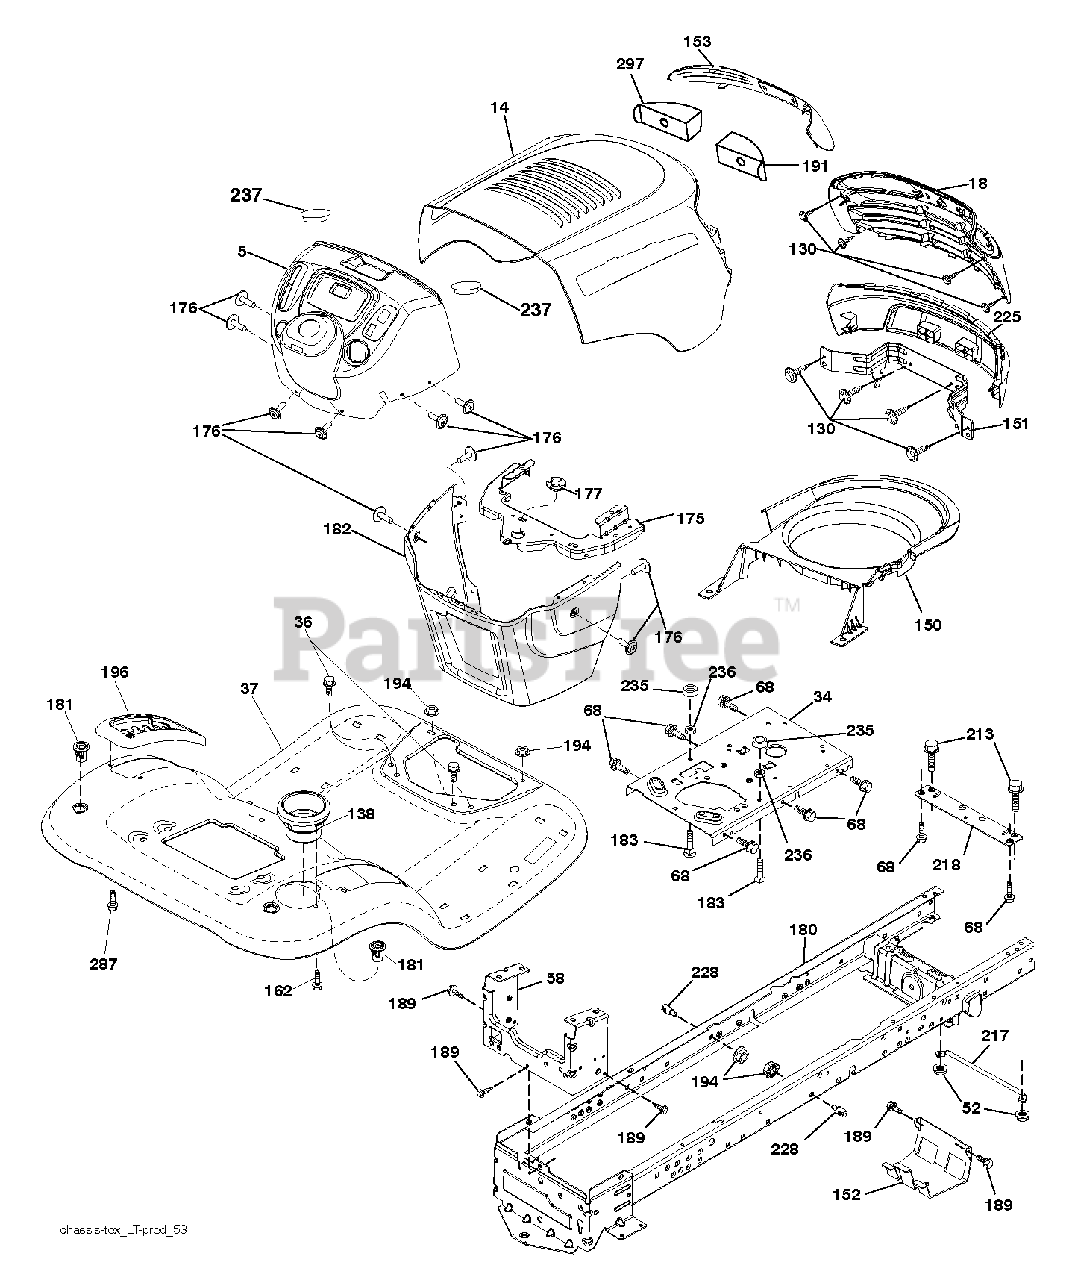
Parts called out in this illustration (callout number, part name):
5	DASH.PRED.LT.CC.ICY.N/SRV.BLK
14	HOOD.PREDATR.LT.U-FRM.TPVNT428
18	GRILLE.SVC.BASE.PREDATOR.LT428
34	PLATE.ENGINE.WELDED.CHASSIS
36	SCREW 5/16"
52	LOCKNUT
58	DRAWBAR UPPER 2PC SMALL FENDER
68	SCREW LT
130	SCREW.#10 X 0.750.BOS THREAD
138	CUPHOLDER.TL.TEX.BLACK
151	BRACKET.PIVOT.ALPHA.LT
152	SHIELD BROWNING
153	LENS.PREDATOR.LT.
162	SCREW.HI-LO.CONSOLE
176	SCREW.#10-24X5/8.RN.QU
177	BUSHING STEERING
180	CHASSIS.WLDMNT.14GA.2PC.18".TI
181	FEND/FTRST.PCH.CPH.NFW
182	DASH.LWER.PREDATOR/HUSQ.LT
183	BOLT.5/16-18X1-1/4 FULL THD
189	SCREW
191	INSERT.REFLECT.PREDATOR.LT.RH
194	NUT LOCK HEX FLANGE 5/16-18
213	BOLT
217	ROD.PIVOT.HOOD
218	X-PIECE.HOOD.STOP.NON/
228	STUD.FASTNER.W/ANTI-ROTATE
235	SPACER FENDER
236	NUT.CENTERLOCK.5/16-
237	PLUG.MOUNT.CARGO.BLK
297	REFLECTOR.INSERT.PRED.LH.LT
